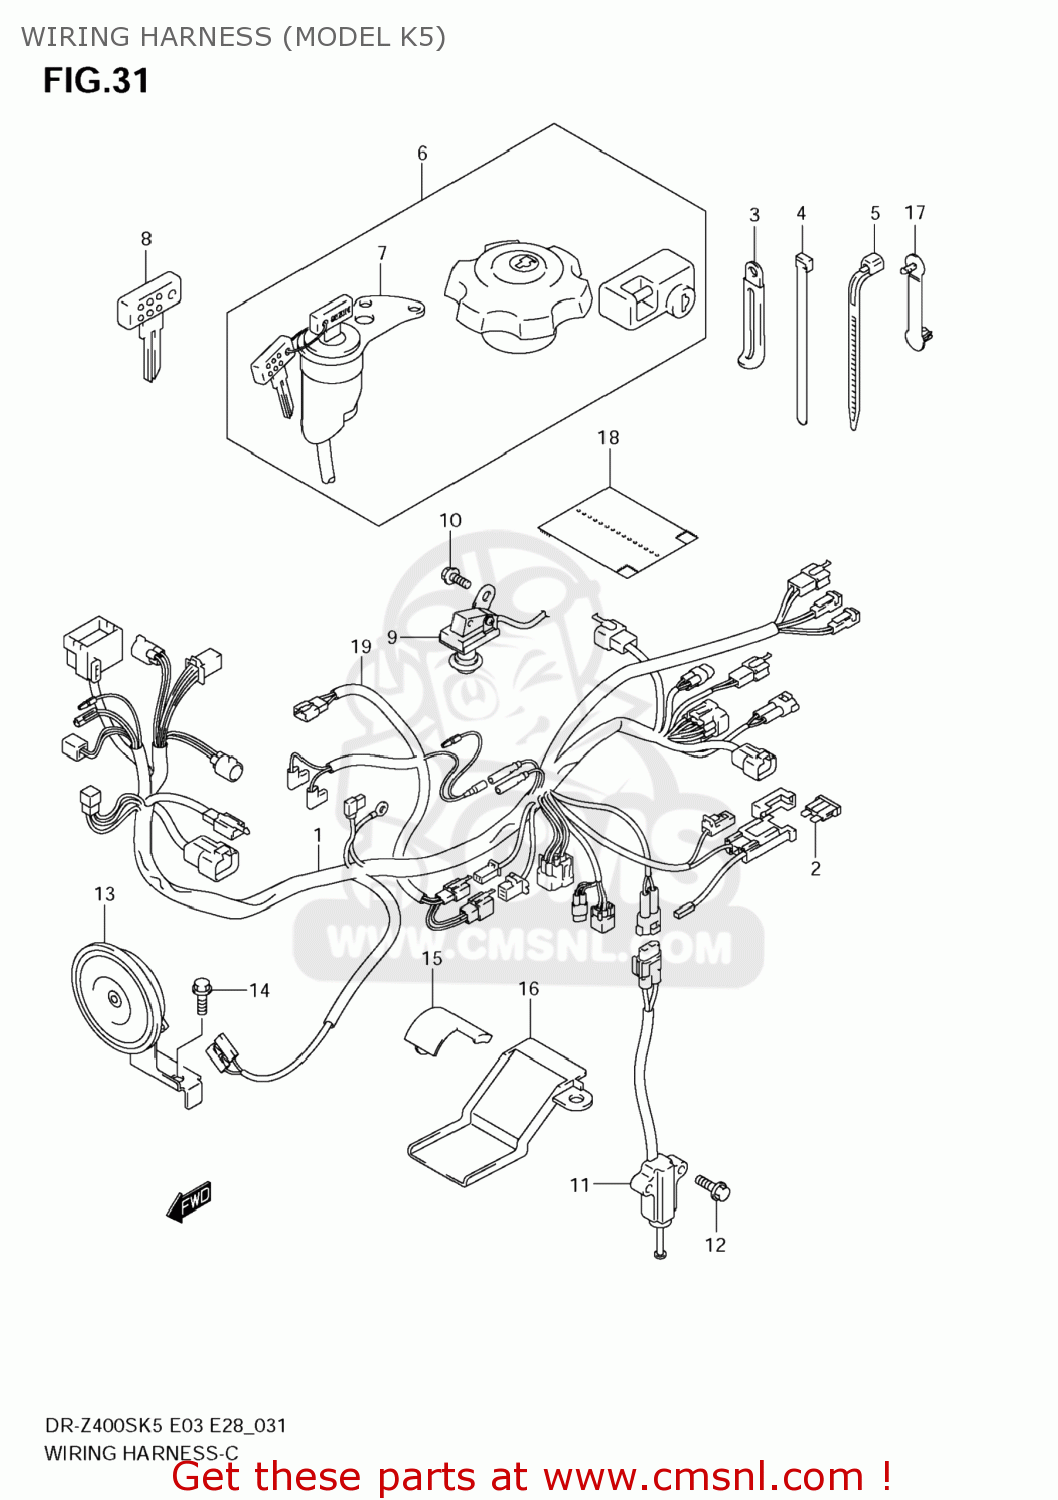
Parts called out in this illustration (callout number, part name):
1	HARNESS,WIRING
2	FUSE(20A)
3	CLAMP(L:45)
4	CLAMP(L:145)
5	CLAMP(L:125)
6	LOCK SET
7	SWITCH ASSY,IGNITION
8	KEY,BLANK(TYPE:C)
9	SWITCH ASSY
10	SCREW
11	SWITCH ASSY,SIDE STAND
12	BOLT
13	HORN ASSEMBLY
14	BOLT
15	PROTECTOR,WIRING HARNESS
16	PROTECTOR,WIRING HARNESS
17	CLAMP(L:63)
18	COVER,WIRING HARNESS
19	WIRE,CARB HEATER
